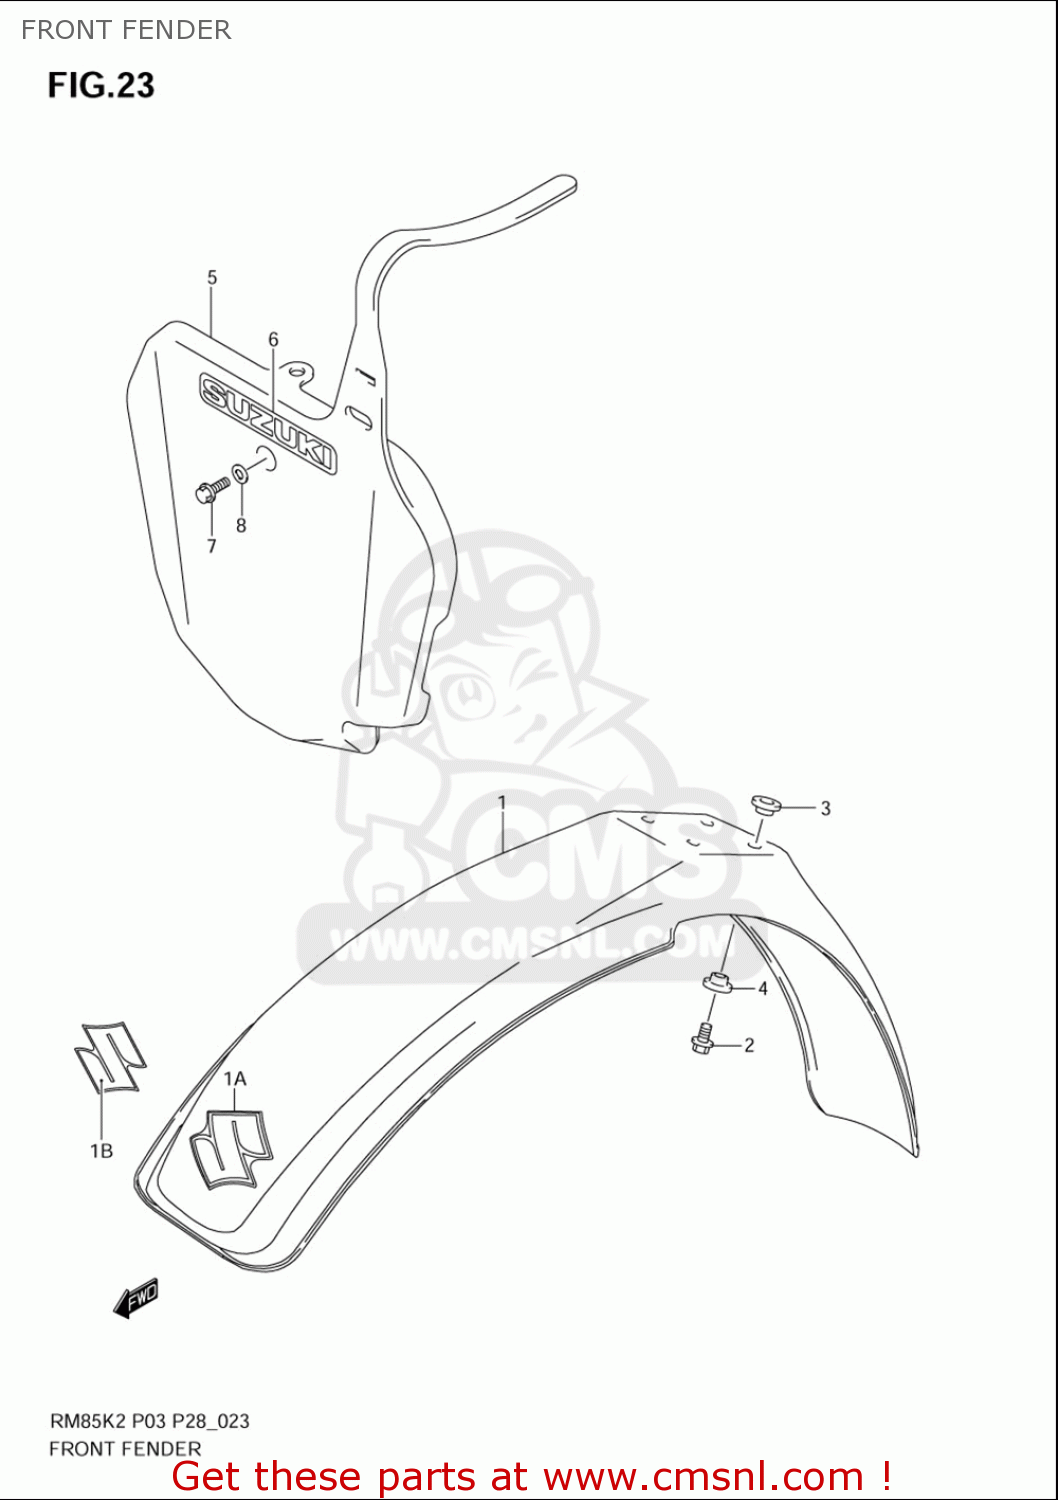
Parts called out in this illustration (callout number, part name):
1	FENDER,FR
1B	EMBLEM,S
2	BOLT,6X20
3	WASHER
4	WASHER
5	PLATE,NUMBER FR
6	EMBLEM,SUZUKI
7	BOLT,6X20
8	WASHER(6.5X14X1.6)
